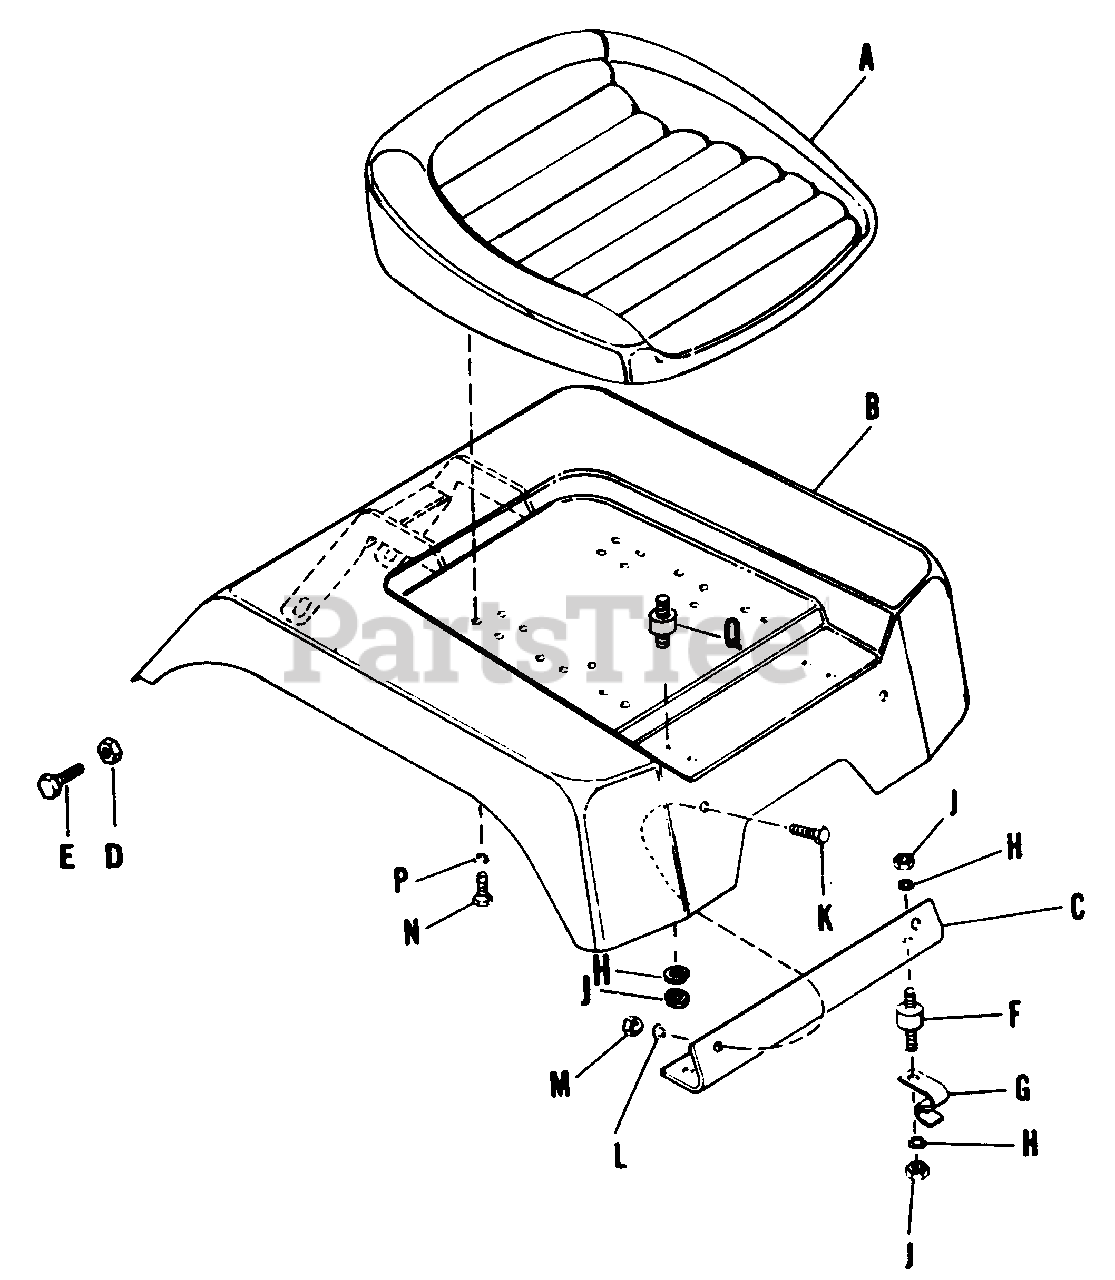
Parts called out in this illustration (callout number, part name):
A	Seat Assembly
B	Seat Deck Assembly
C	Seat Deck Bracket, Front
D	Hex Locknut, Full, 3/8"-16
E	Hex. Head Capscrew, 3/8"-16 x 1-1/4
F	Cushion Connector, Front
G	Spring Clip
H	Lock Washer 5/16"
J	Hex. Nut, Full, 5/16"-18
K	Hex. Head Capscrew, 5/16" 18 x 5/8" lg.
L	Lockwasher 5/16"
M	Hex. Nut Full, 5/16"-18
N	Hex. Head Capscrew, 5/16"-18 x 5/8" lg.
P	Lockwasher 5/16"
Q	Cushion Connector, Front
